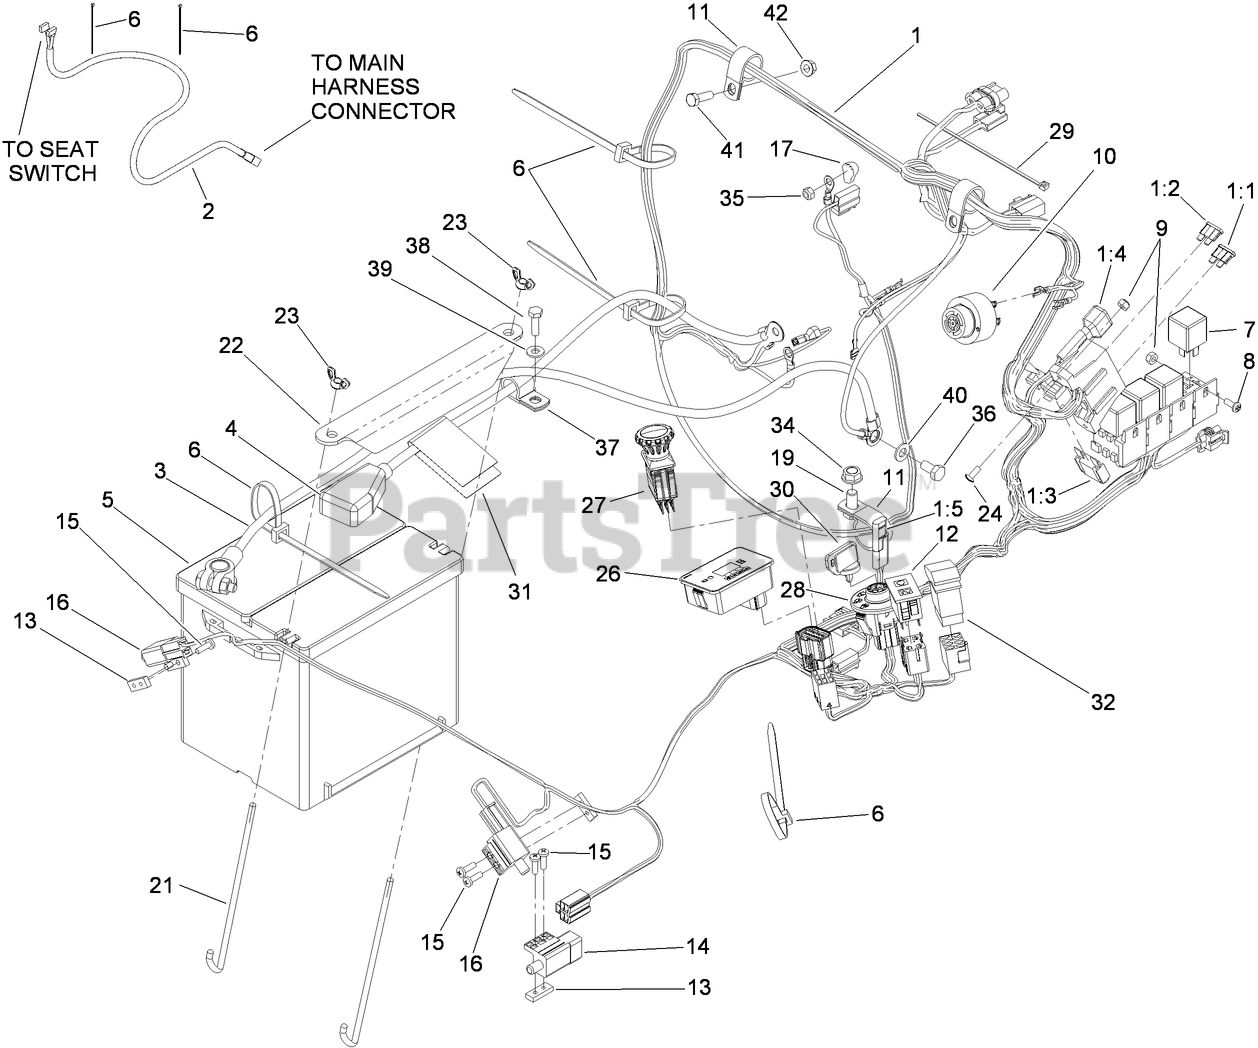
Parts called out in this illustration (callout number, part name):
1	HARNESS-WIRE
1:1	FUSE-BLADE, 10 AMP
1:2	FUSE-BLADE, 30 AMP
1:3	FUSE-BLADE, 50 AMP
1:5	CAP-PLUG
2	HARNESS-WIRING, SEAT
3	CABLE-BATTERY, NEGATIVE
4	CABLE-BATTERY, POSITIVE
5	BATTERY-DRY
6	TIE-CABLE
9	NUT-LOCK, NI
10	ALARM-TONE, DUAL
11	CLIP-LOOM
12	LAMP-WARNING
13	PLATE-TAPPED
14	SWITCH
15	SCREW-PPH
16	SWITCH-OPEN, NORMALLY
17	CAP-INSULATOR, RED
19	SCREW-HH
21	BOLT-HOLDDOWN
22	HOLDDOWN-BATTERY
23	WINGNUT
24	SCREW-HEAD, TRUSS
26	MODULE ASM
27	SWITCH-PTO, 10 AMP
28	SWITCH-IGNITION
29	TIE-CABLE
30	KEY-IGNITION
31	DECAL-BATTERY CHARGING
32	SWITCH-ROCKER
34	NUT-HHF, WHIZ
35	NUT-LOCK
36	SCREW-HH
37	CLIP-LOOM
38	SCREW-HH
39	WASHER-FLAT
40	WASHER-PLAIN
41	SCREW-HH
42	NUT-HF
